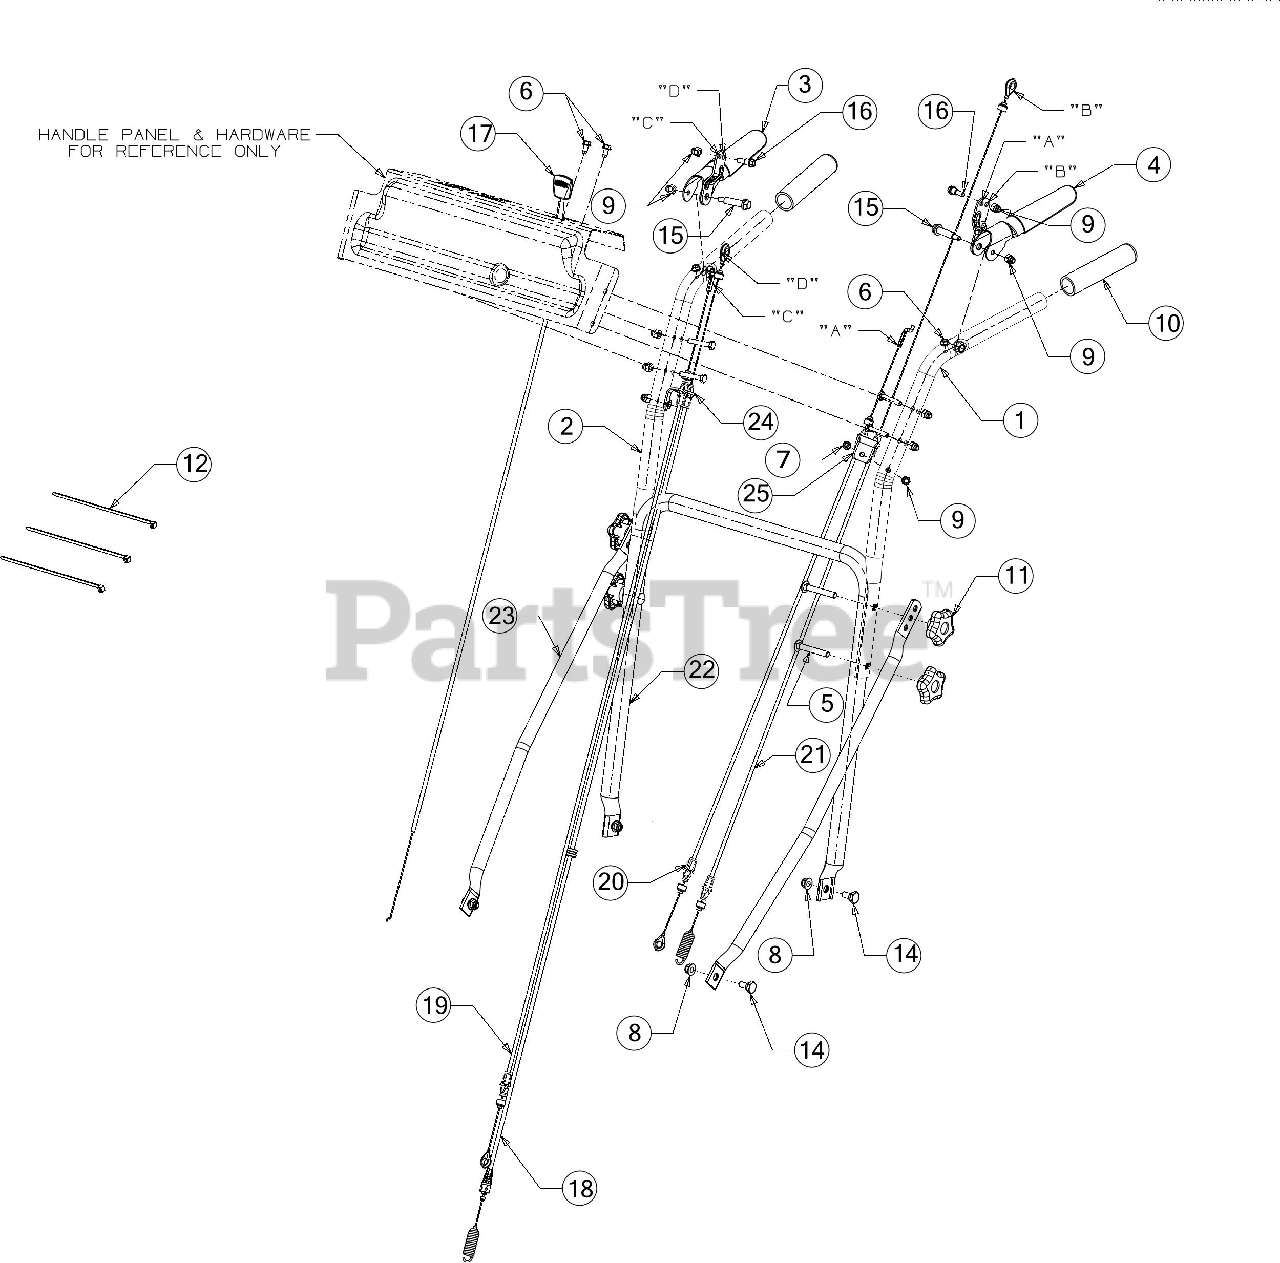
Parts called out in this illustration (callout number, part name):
1	UPPER HANDLE ASSEMBLY (LH)
2	UPPER HANDLE ASSEMBLY (RH)
3	LEVER ASSEMBLY (RH)
4	LEVER ASSEMBLY (LH)
5	SCREW 5/16-18 X 2.25 GR5
6	SCREW 1/4-20 X.500
7	SCREW 1/4-20 X 1.50 GR.5
8	FLANGE LOCK NUT 5/16-18
9	HEX ACORN NUT
11	STAR KNOB 5/16-18
12	CABLE TIE 7"
14	SHOULDER SCREW .437
15	SHOULDER BOLT .375 X 1.285:1/4-20
16	SHOULDER SCREW .342 X .335 X 1/4-20
17	THROTTLE/CHOKE CABLE 38 X 1.1"
18	BLADE CONTROL CABLE
19	TRANSMISSION BRAKE CABLE (RH)
20	TRANSMISSION BRAKE CABLE (LH)
21	WHEEL CLUTCH CABLE
23	HANDLE ADJUSTMENT BRACE
24	CABLE BRACKET MOUNTING (RH)
25	CABLE BRACKET MOUNTING (LH)
